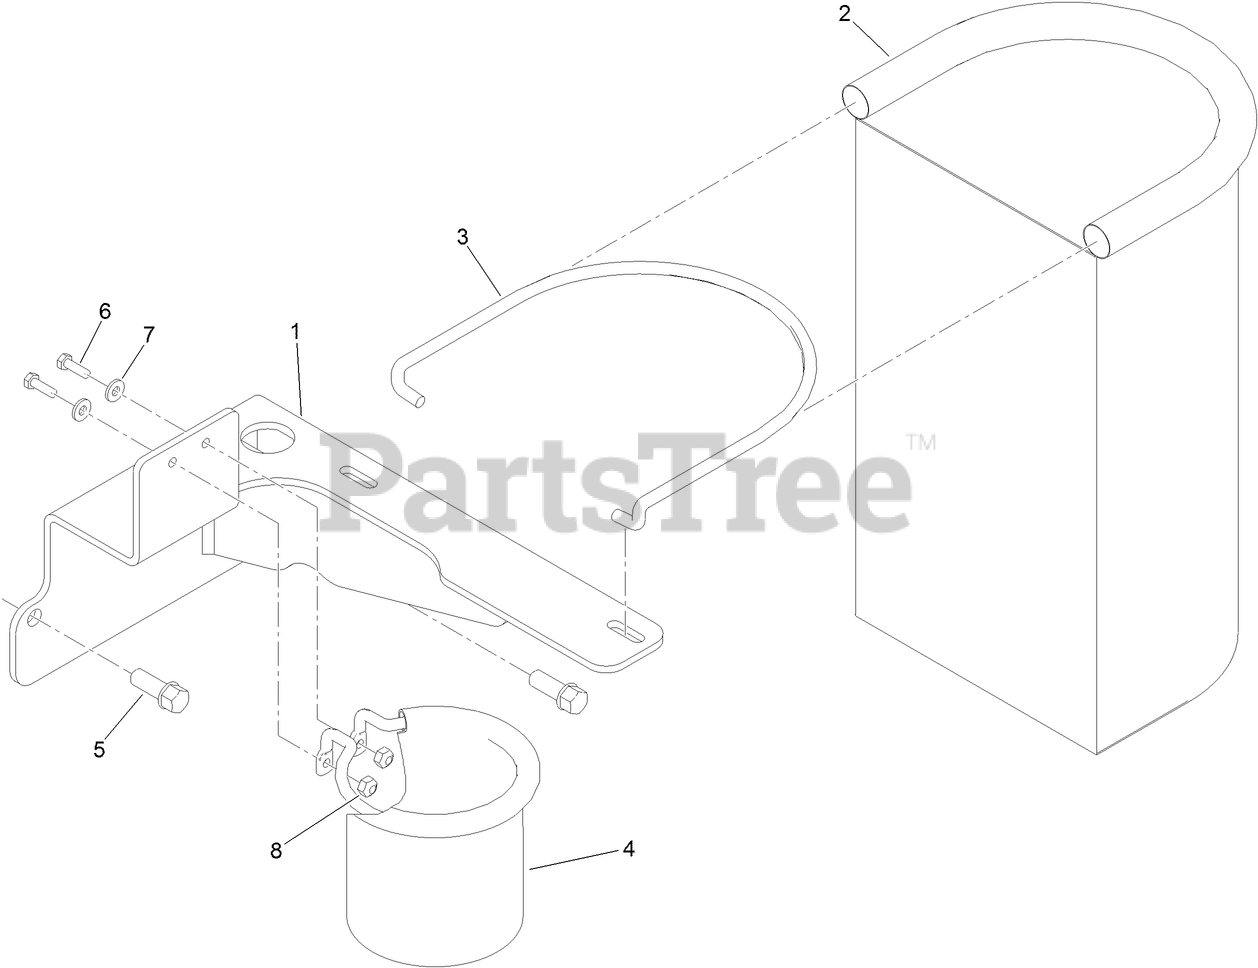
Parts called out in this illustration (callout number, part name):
1	TRASH BAG BRACKET ASM
2	BAG-TRASH
3	ROD-BAG, TRASH
4	HOLDER-BAG
5	SCREW-HWH
7	WASHER-FLAT
8	NUT-LOCK, NI
